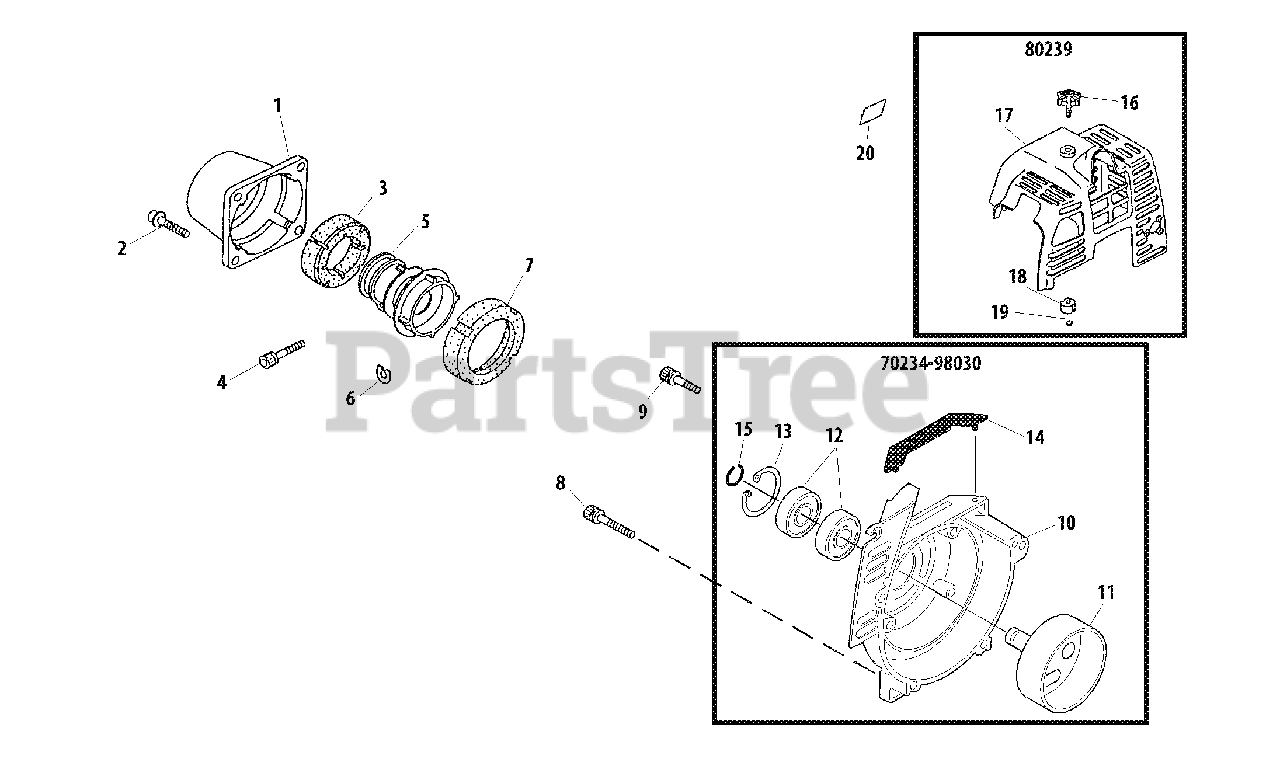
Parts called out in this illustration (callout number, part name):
1	CAP
2	SCREW - 5X16
3	CUSHION - FRONT
4	SCREW - 5X25
5	CLAMP, MAIN PIPE
6	SHIM
7	CUSHION - REAR
8	SCREW - 5X35
9	SCREW - 5X16
10	CASE, FAN
11	DRUM, CLUTCH
12	BEARING, BALL - 6000
13	RING, RETAINING - 26
14	CUSHION
15	RING, RETAINING
16	THUMBSCREW
17	COVER, ENGINE
18	INSULATOR
19	CLIP
70234-98030	FAN CASE ASSY
80239	ENGINE COVER KIT
